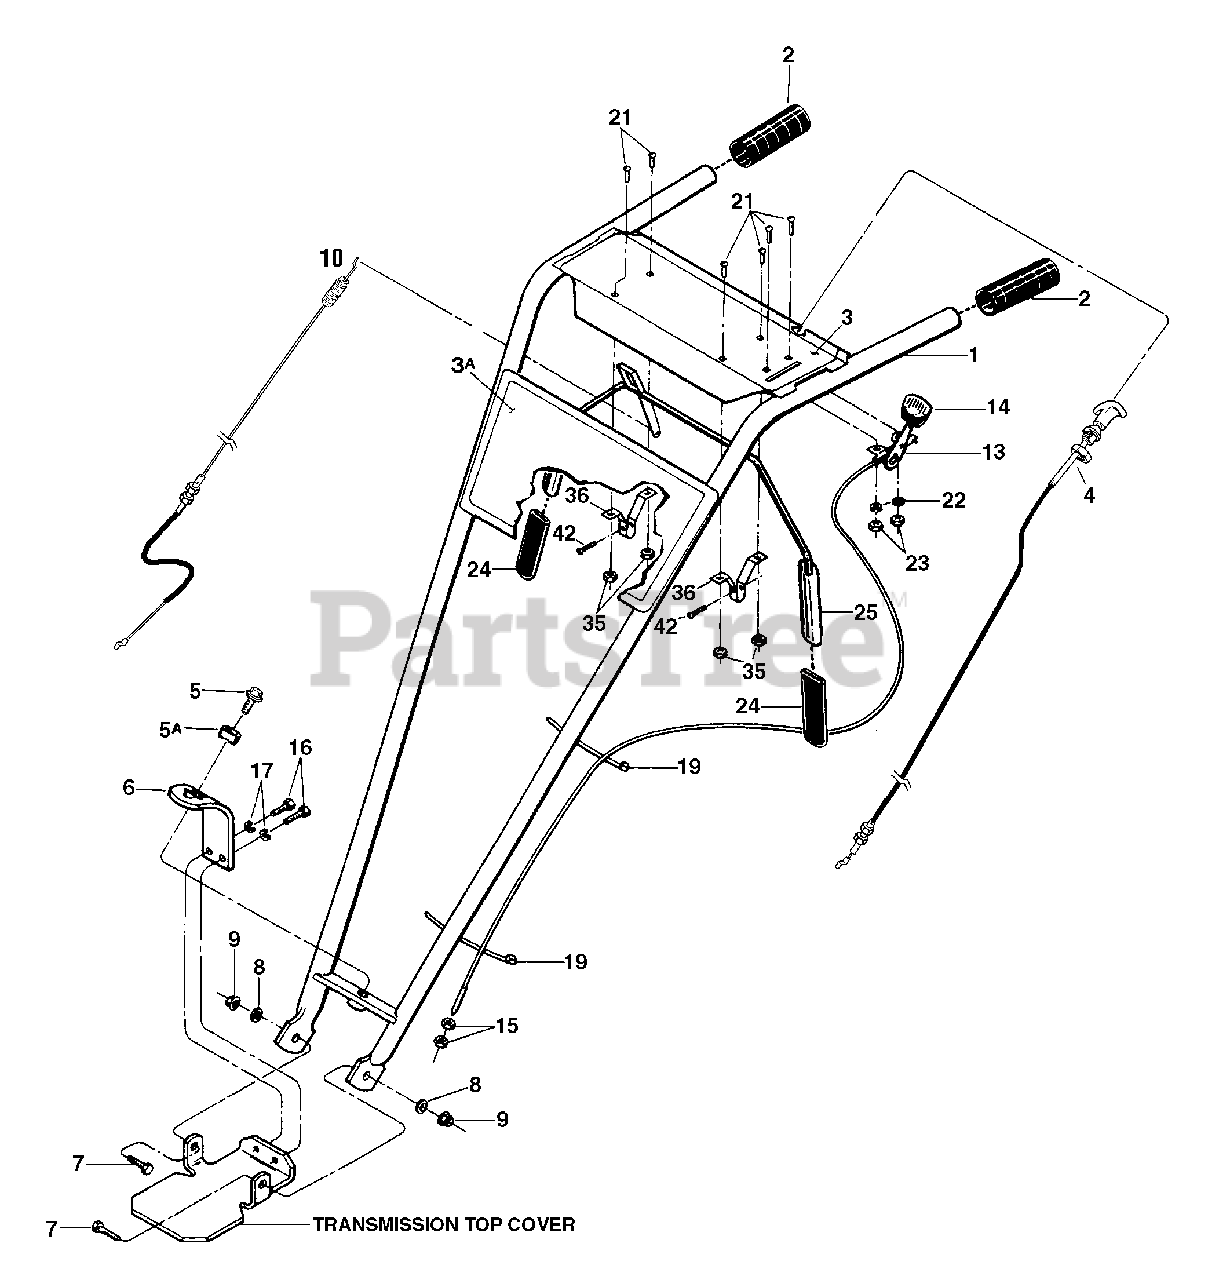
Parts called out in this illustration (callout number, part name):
1	Handlebars
2	Grip
3	Decal, Control Panel
3A	Decal, Model Name/Logo
4	Reverse Clutch Control Cable
5	Height Adjustment Screw
5A	Washer, Keyed
6	Bracket, Handlebar Height Adjustment
7	Hex Hd. Screw, 3/8-16 x 1
8	Washer, Plain (flat) 3/8, S.A.E.
9	Hex Locknut, 3/8-16
10	Cable, Forward Clutch Control
13	Wheel Gear Control and Cable Assy
14	Knob, Wheel Gear Control Lever
15	Hex Nut, 5/16-24
16	Hex Hd. Screw, 3/8-16 x 5/8
17	Lockwasher, 3/8
19	Cable Ties, Plastic
21	Round Hd. Screw, #10-32 x 1/2
22	Lockwasher, #10
23	Hex Nut, #10-32
25	Bail, Forward Clutch Control
36	Bracket, Bail Support
42	Hex Flange Screw, self-tapping, 1/4-20 x 1/2
